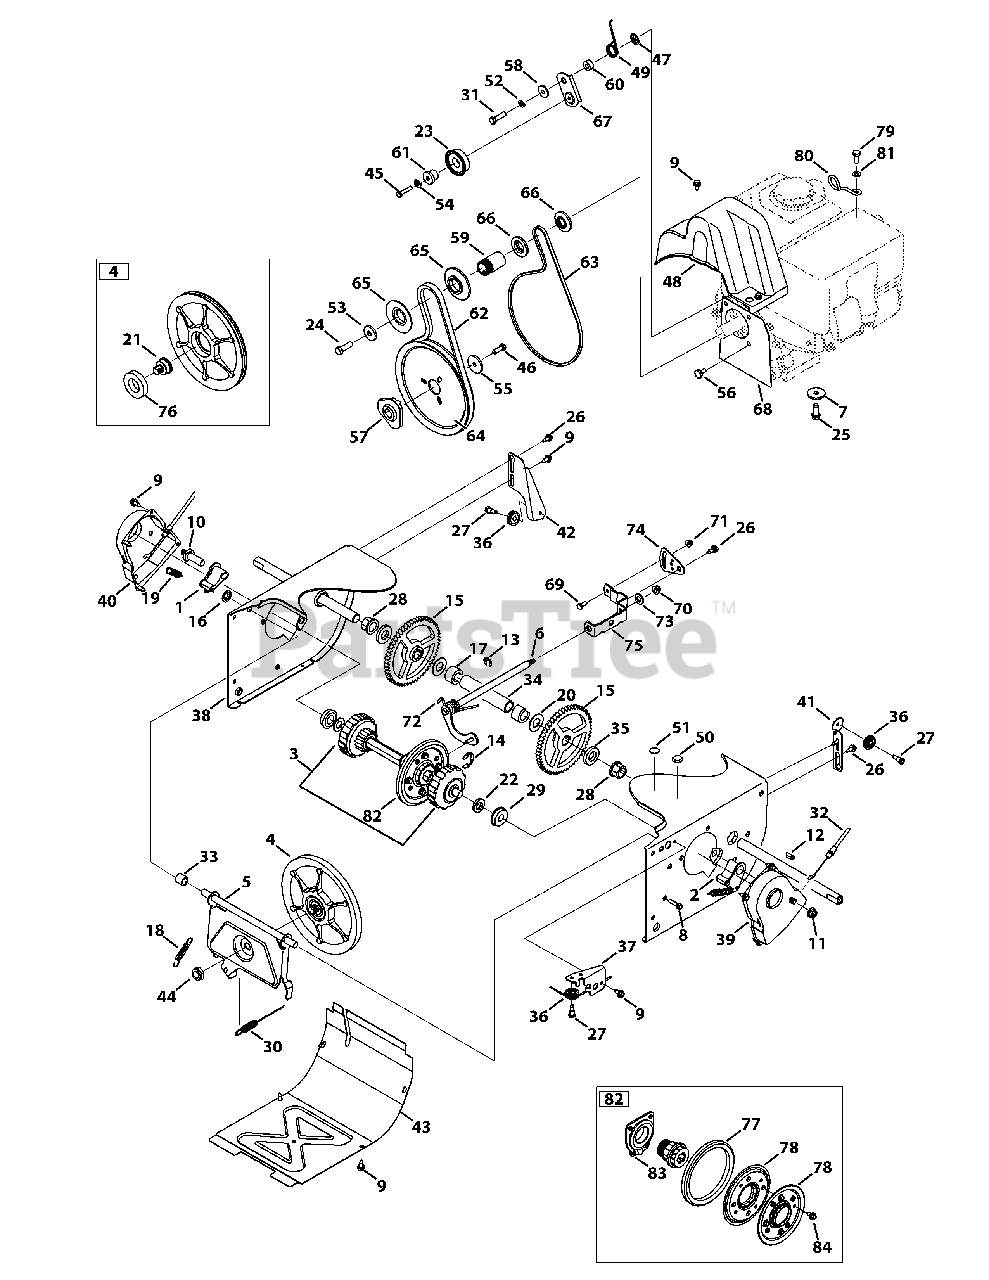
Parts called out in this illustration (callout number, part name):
1	Dogg Assembly, RH
2	Dogg Assembly, LH
3	Drive Shaft Assembly
4	Friction Wheel Disc Assembly
5	Friction Wheel Support
6	Rod Shift Assembly
7	Washer, Flat, .38 x 1.38
8	Screw, 1/4-20 x 1.000
9	Screw, 1/4-20 x .625
10	Actuator Shaft
11	Nut, Flangelock, 3/8-16
12	Hi-Pro Key, 3/16 x 3/4 DIA
14	Retainer Ring
16	Nut, Speed, .500
17	Spacer, .76 x .75
18	Extension Spring, .380 x 2.500
19	Extension Spring, .500 x 1.71
20	Washer, Flat, .76 x 1.49
21	Friction Pin, Disc Bearing
22	Spacer, .68 ID x 1.25 OD x .20
23	Pulley Assembly
24	Hex Head Screw, 3/8-24 x 1.25
25	Taptite Sems Screw, 3/8-16 x 1.000
26	Screw, Shoulder, .368 x .113 x 1/4-20
27	C Screw, Shoulder, .340 x .335 x 1/4-28
28	Hex Flange Bearing, .75 ID
29	Ball Bearing, 17 x 40 x 12
30	Drive Clutch Cable
31	Hex Head Screw, 5/16-24 x 1.25
32	Steering Cable
33	Spacer, .508 x .75
34	Axle Support Tube
35	Spacer, Axle
36	Roller Cable
37	Auger Cable Guide Bracket
38	Wheel Drive Frame
39	Shaft Retainer, LH
40	Shaft Retainer, RH
41	Auger Clutch Cable Guide Bracket
42	Drive Clutch Cable Guide Bracket
44	Nut, Flange, 5/8-18
45	Taptite Screw, 1/4-20 x 1.250
46	Hex Head Screw, 5/16-24 x .875
47	Nut, Push-On, .25 DIA
48	Belt Cover
49	Spring, Torsion, .850 x .333
50	Plug, 3/8 ID
51	Plug, 1/2 ID
52	Washer, Lock, 5/16
53	Washer, Flat, .45 x 1.5
54	Washer, Lock, 1/4
55	Washer, Flat, .34 x 1.50
56	Screw, Shoulder
57	Pulley Adapter, .75 DIA
58	Spacer, Shoulder, .3175 x .500
59	Spacer, .875 x 1.185
60	Spacer, .340 x .750
61	Spacer, Shoulder, .260 x .785
62	Belt, .500 x 35.06
63	V Belt, 3/8 x 35"
64	Auger Pulley, 8.1 x .5
65	Pulley, Half, 4L-V x 2.600
66	Pulley, Half, 3/8-V x 2.2
67	Drive Idler Bracket
68	Cover Plate
69	Hex Head Screw, 1/4-20 x .620
70	Nut, Flangelock, 5/16-18
71	Nut, Flangelock, 1/4-20
72	Spring, Torsion, .750 x .968
73	Washer, Flat, .469 x .875 x .105
74	Speed Selector Pivot Bracket
75	Speed Selector Shift Bracket
76	Ball Bearing, 30 x 55 x 13
77	Friction Wheel, 5.5 OD
78	Friction Wheel Plate
79	Hex Head Screw, 1.25 x 20
80	Cable Control Wire
81	Washer, Flat, .330 x .630
82	Friction Wheel Assembly
83	Bearing Assembly, Friction Wheel
84	Screw, 5/16-18 x .750
